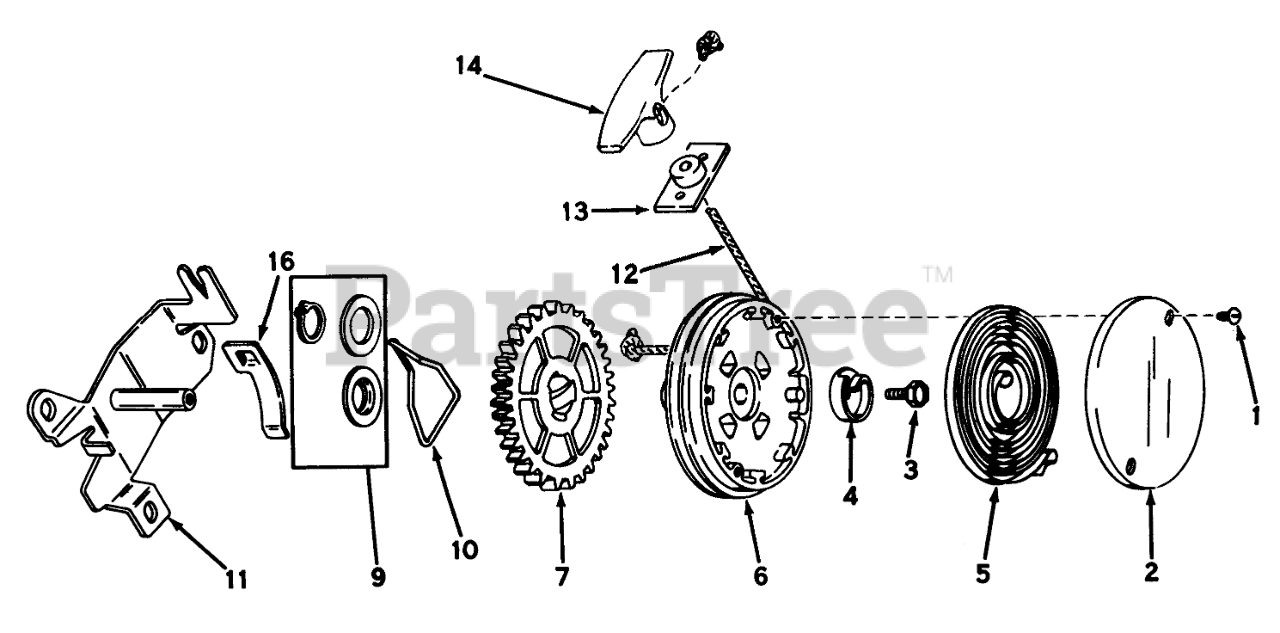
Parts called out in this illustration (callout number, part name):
1	Screw, Cover
2	Cover, Spring
3	Screw, Hex Washer Head
4	Hub Spring
5	Spring, Rewind
6	Pulley Assy. (Incl. #9)
7	Gear
9	Kit, Thrust Wash. & Snap Rg.
11	Bracket Assy. Mounting
12	Rope, Starter
13	Bracket Assy.
14	Handle-Starter
16	Clip Rope
